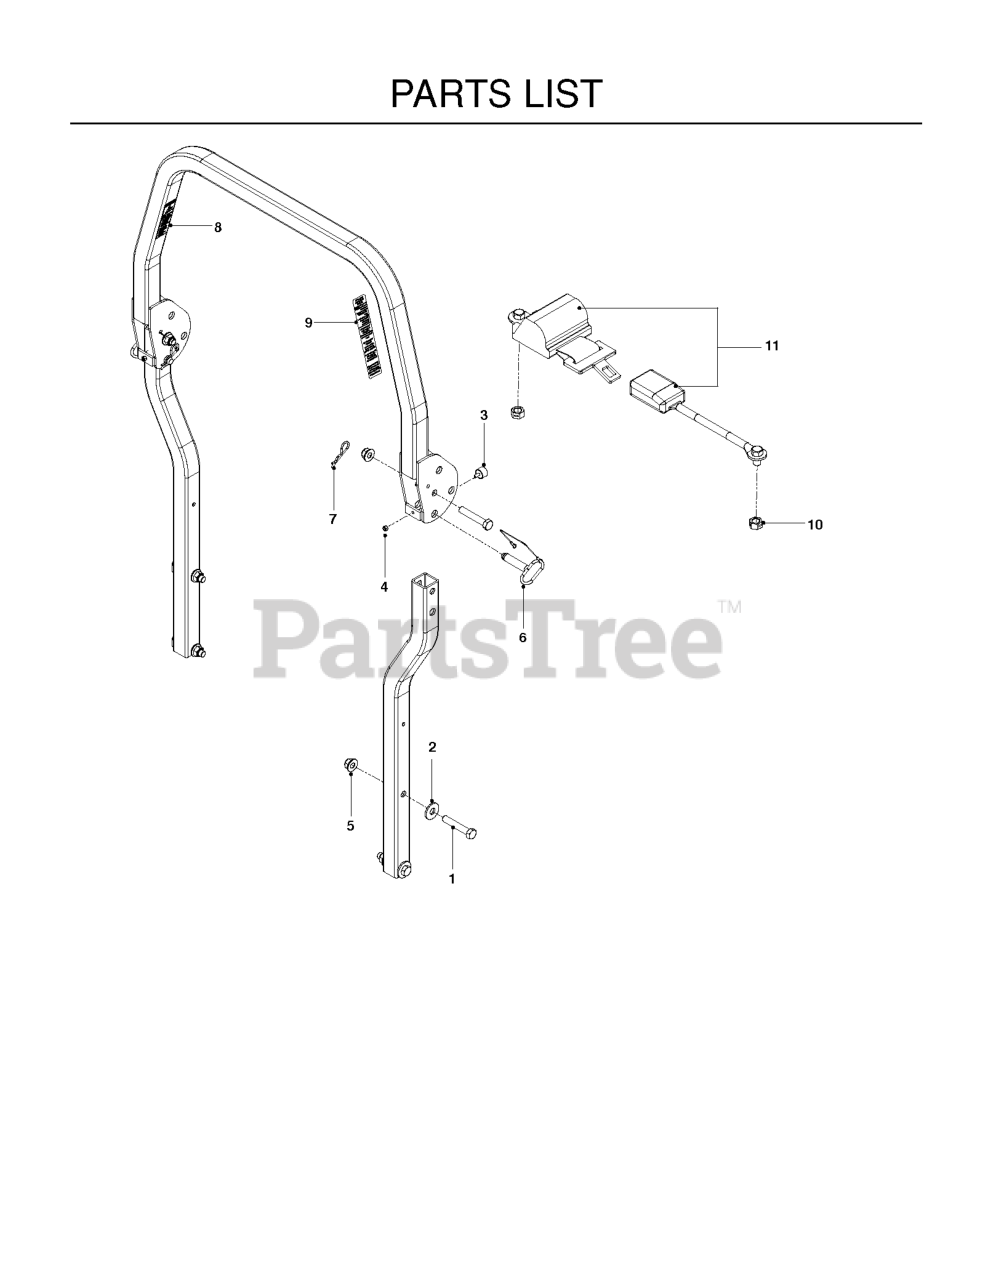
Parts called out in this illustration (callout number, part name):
1	5/8-11 X 3-1/2 HHB GRADE 5
2	WASHER, 5/8 FLAT
3	BUMPER, MALE STUD, 1/4-20
4	NUT.1/4-20.HEX.NYLOC.ZD
5	NUT 5/8-11 FLG NYLOC ZD
7	PIN HAIR .148 X 2-15/16 #210
8	DECAL, ROPS, WARNING
9	DECAL, ROPS MFG REQUIREMENTS
10	NUT HEX 7/16F LOCK RP
11	SEAT BELT, RETRACTABLE
